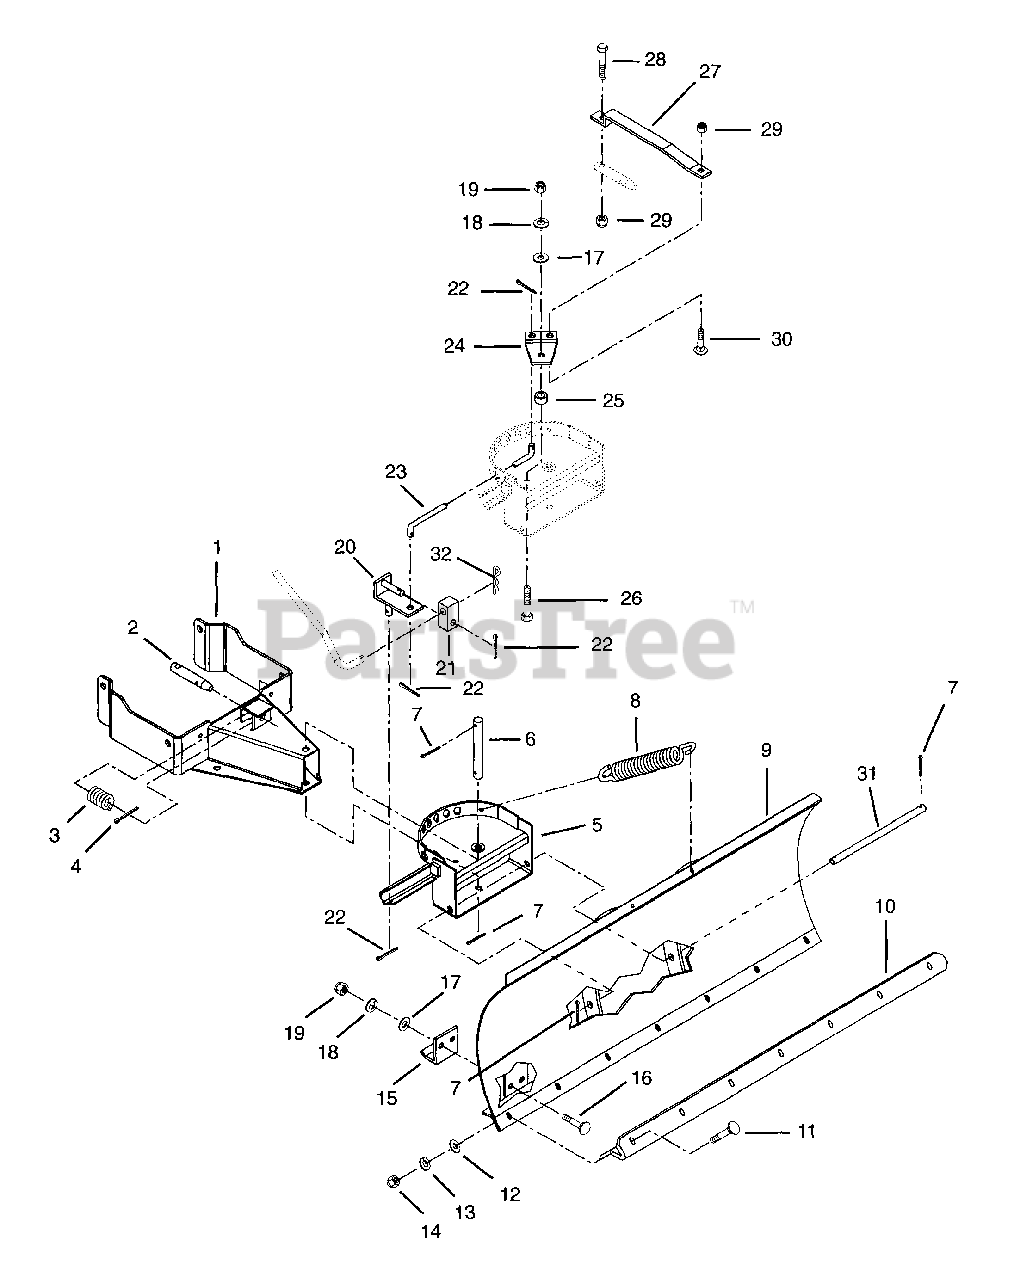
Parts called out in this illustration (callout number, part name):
1	Frame-Push
2	Latch Pin
3	Spring-Compression .080 x .85 x 1.44
4	Pin-Cotter .12 x 1.0
7	Pin-Cotter .18 x 1.0
8	Spring-Tension .187 x .50 x 9.94
10	Wear Plate
11	Bolt-Round Head Square Neck .31-18 x 1.00
12	Washer-Flat-Steel .38 x .875 x .083
13	Washer-Locking .31 x .078
14	Bolt-Round Head Square Neck .31-18 x 1.00
15	Skid Shoe
16	Bolt-Round Head Square Neck .38-16 x 1.0
17	Washer-Flat-Steel .438 x 1.0 x .083
18	Washer-Locking .375 x .094
19	Nut-Hex .375-16
21	Universal Block Joint
22	Pin-Cotter .12 x .75
24	Pivot Plate
25	Spacer .406 x .749 x .162
26	Bolt-Hex .38-16 x 1.00 Grade 5
28	Bolt-Hex .31-18 x 1.25 Grade 5
29	Nut-Locking-Center .31-18
30	Bolt-Round Head Square Neck .31-18 x .75 Grade 2
32	Pin-Hair-Internal .08 x .18 x 1.18
